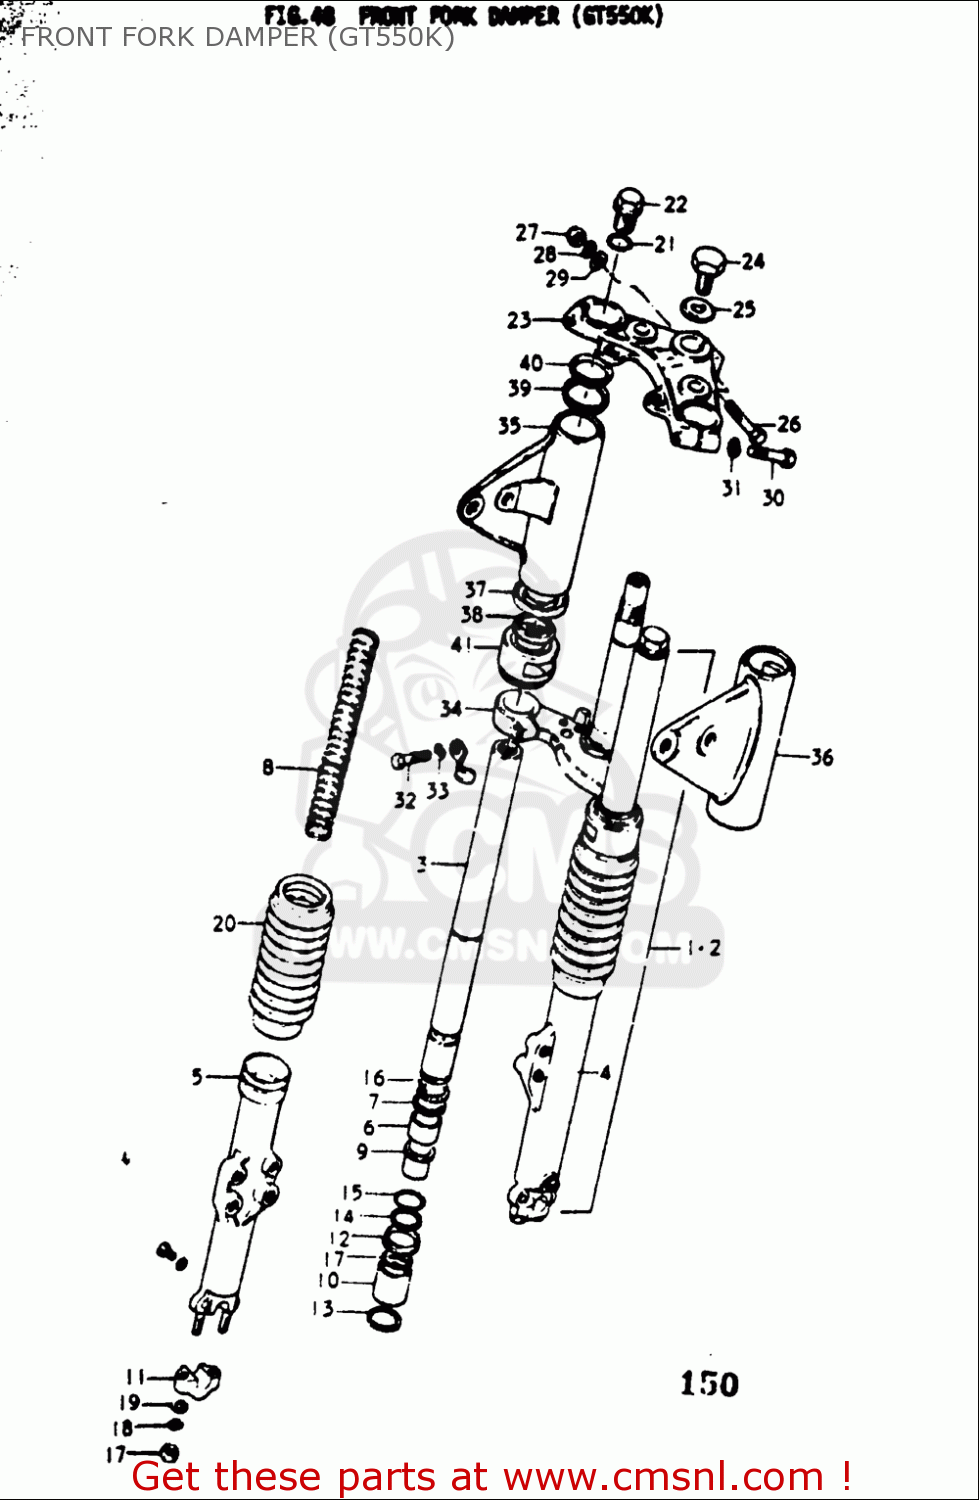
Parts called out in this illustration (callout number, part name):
6	SEAL,OIL 35X48X11
7	RING,FR FORK
11	HOLDER,AXLE
17	NUT
18	WASHER,LOCK
19	WASHER
20	BOOT
21	O RING
22	CAP,INNER TUBE
26	BOLT
27	NUT
28	WASHER,LOCK
29	WASHER
30	BOLT
31	WASHER,LOCK
32	BOLT
33	WASHER,LOCK
37	GUIDE
38	CUSHION,HEADLAMP BRACKET
39	GUIDE
40	CUSHION,HEADLAMP BRACKET UPR
